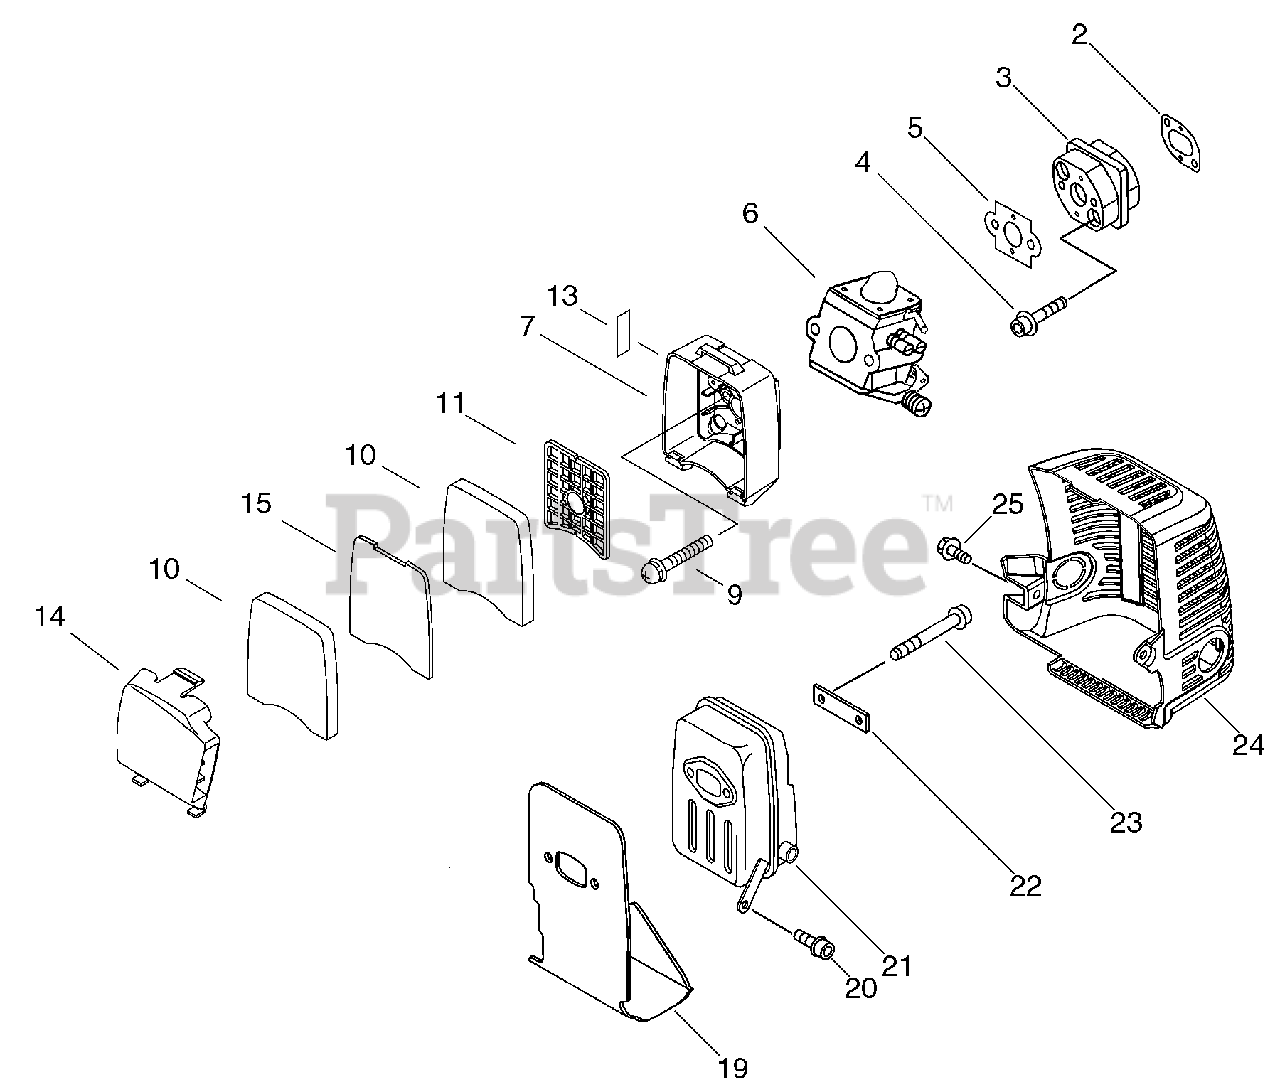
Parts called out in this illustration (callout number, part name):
2	GASKET, INTAKE
3	INSULATOR, INTAKE
4	SCREW - 5X25
5	GASKET, INTAKE
6	CARBURETOR C1Q-K73A
7	CASE, AIR FILTER
9	SCREW - 5X50
10	FILTER, AIR
11	GRID, AIR FILTER
13	LABEL - CHOKE
14	COVER, AIR FILTER
15	FILTER, AIR
19	GASKET, EXHAUST
20	SCREW - 5X12
21	MUFFLER
23	SCREW - 6X60
24	COVER, EXHAUST
25	SCREW - 5X12
